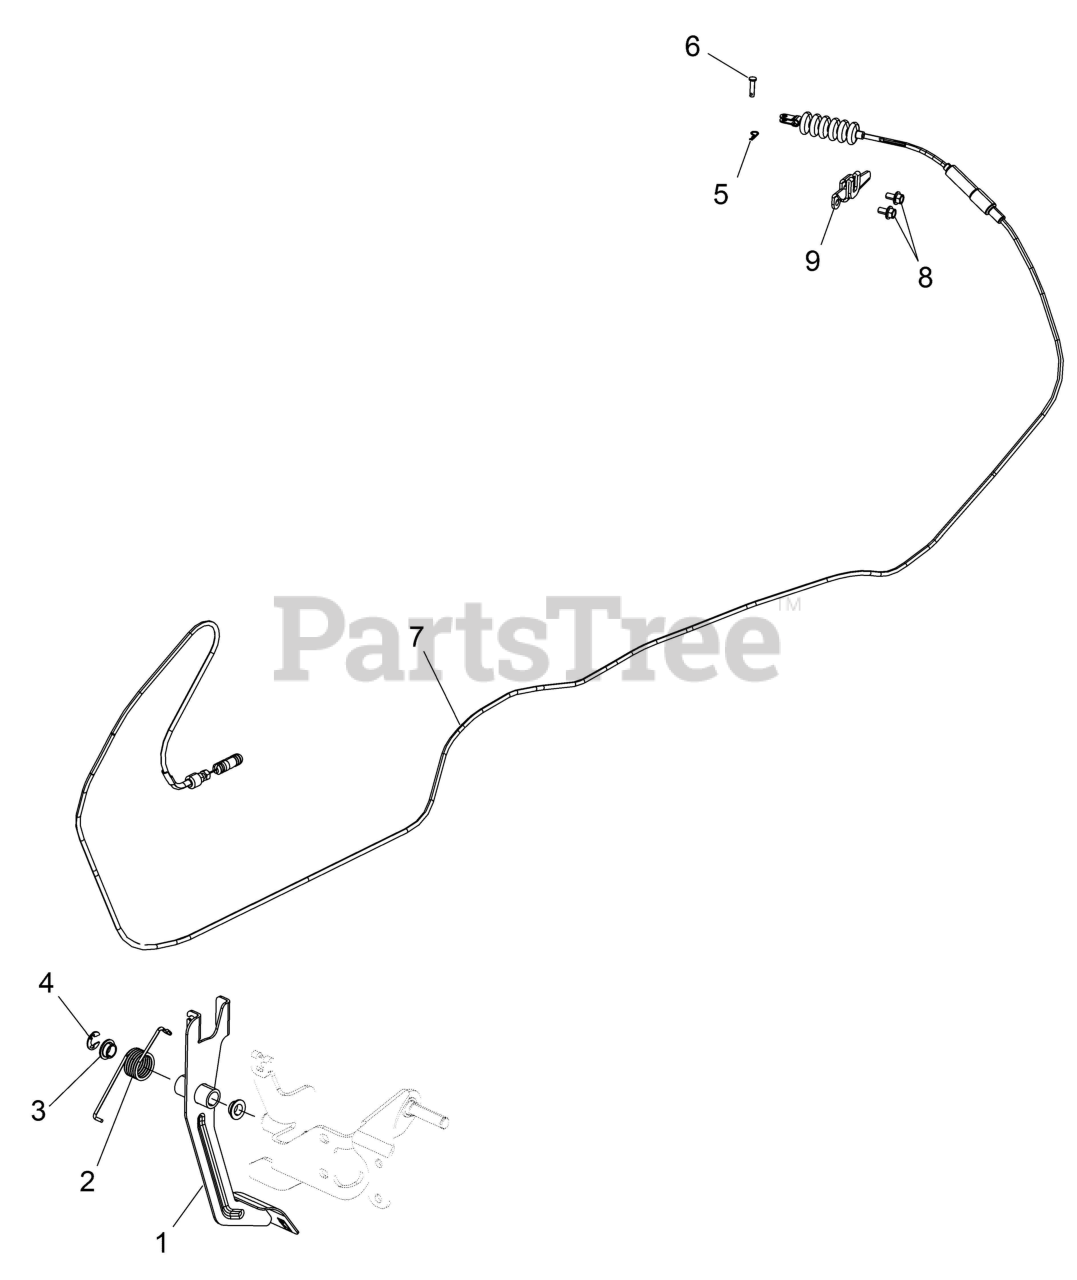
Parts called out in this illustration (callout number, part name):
1	WELD-THROTTLE PEDAL,BLK
2	SPRING-ACCELERATOR,HEAVY
3	BUSHING-PEDAL PIVOT
5	HAIRPIN-COTTER 3/16-1/4
6	PIN,CLEVIS
7	CABLE-THROTTLE,DSL
9	BRKT-THROTTLE,ENGINE
